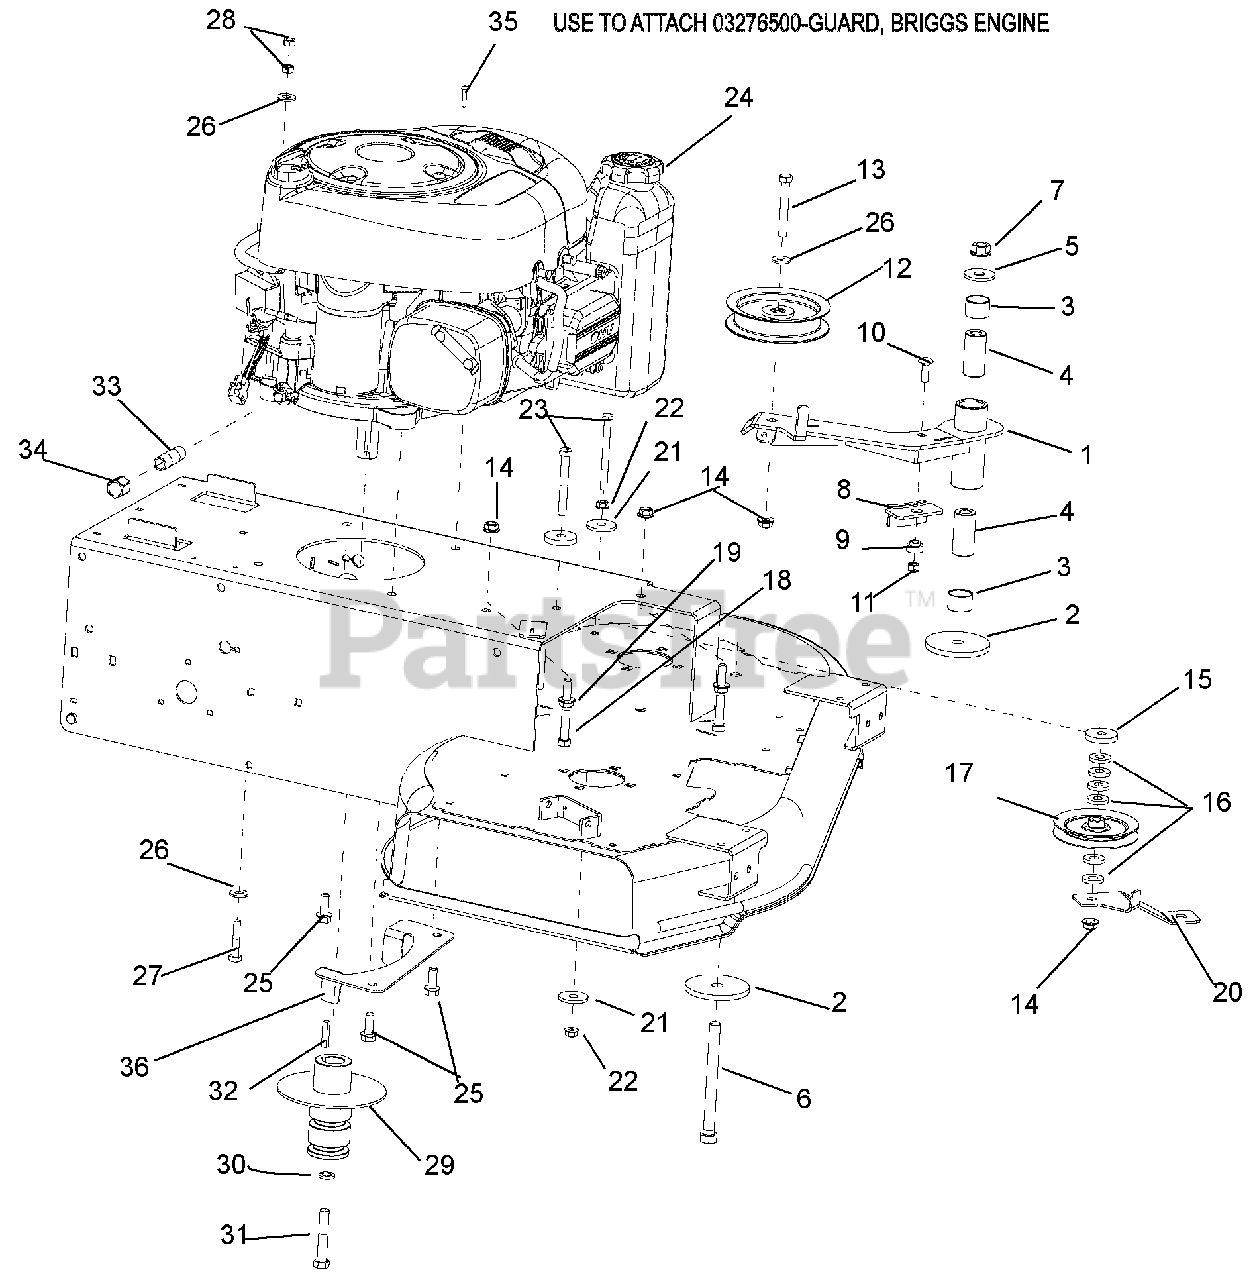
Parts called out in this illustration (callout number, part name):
1	WMT-ARM, PTO IDLER
2	WASHER, FLAT .531X3.000X.25
3	BRG, 1.00 X 1.12 X .75
4	BSHG, SPCR .502X.997X2.03 PM
5	WSHR-FL-STL.511X1.441X.125 YWZ
6	@BLT-HEX .50-13X5.50 GR5YWZC
7	@NUT-LK-TOP-FLG .50-13 YWZC
8	ASSEMBLY-BRAKE PAD
9	BUSHING-FLANGE
10	@BLT-RDHDSQNK .31-18X1.00 G5YZ
11	@NUT-LK-NYL .312-18 YWZC
12	ASM, IDLER 4"
13	@BLT-HEX .38-16X2.75 GR5 YWZC
14	@NUT-LK-TOP-FLG .38-16 YWZC
15	WSHR,FLT STL.406X1.50X.245YWZC
16	WSHR,FLT .438X1.00X.160 ZCC
17	IDLER-V 4.00 X .38 NWHAMSHR
18	@BLT-HEX .38-16X3.00 GR5 YWZC
19	@NUT-SPNLK-FLG .375-16 YWZC
20	BRKT-IDLER BRACE
21	WSHR-FL-STL .406X1.375X.135 YZ
22	@NUT-SPNLK-FLG .312-18 YWZC
23	@BLT-HEX .31-18X3.50 GR5 YWZC
24	ENGINE, WAW 10.5 HP 49 STATE
24	ENGINE,WAW(07 BUILD-AHEAD CARB
25	@SCR-TAP .38-16X1.00 HWH TR YZ
26	@WSHR-FL-STL.38X.875X.083 YWZC
27	@BLT-HEX .31-18X1.75 GR5 YWZC
28	@NUT-LK-CTR .31-18 YWZC
29	PULLEY, WAW DECK/GROUND DRIVE
30	@WSHR-LK .44X.109 REG YWZC
31	BLT-HEX .44-20X2.50 G5 YZ EP80
32	KEY-SQ .25 X 1.25 X .25 SAE
33	3/8X2 SCH40 BLK PIPE NIPPLE
34	3/8 BLK PIPE CAP CZ
35	SCREW, 8-16X.87 PHPAN 3 LOBE
36	BRKT-BELT FINGER
